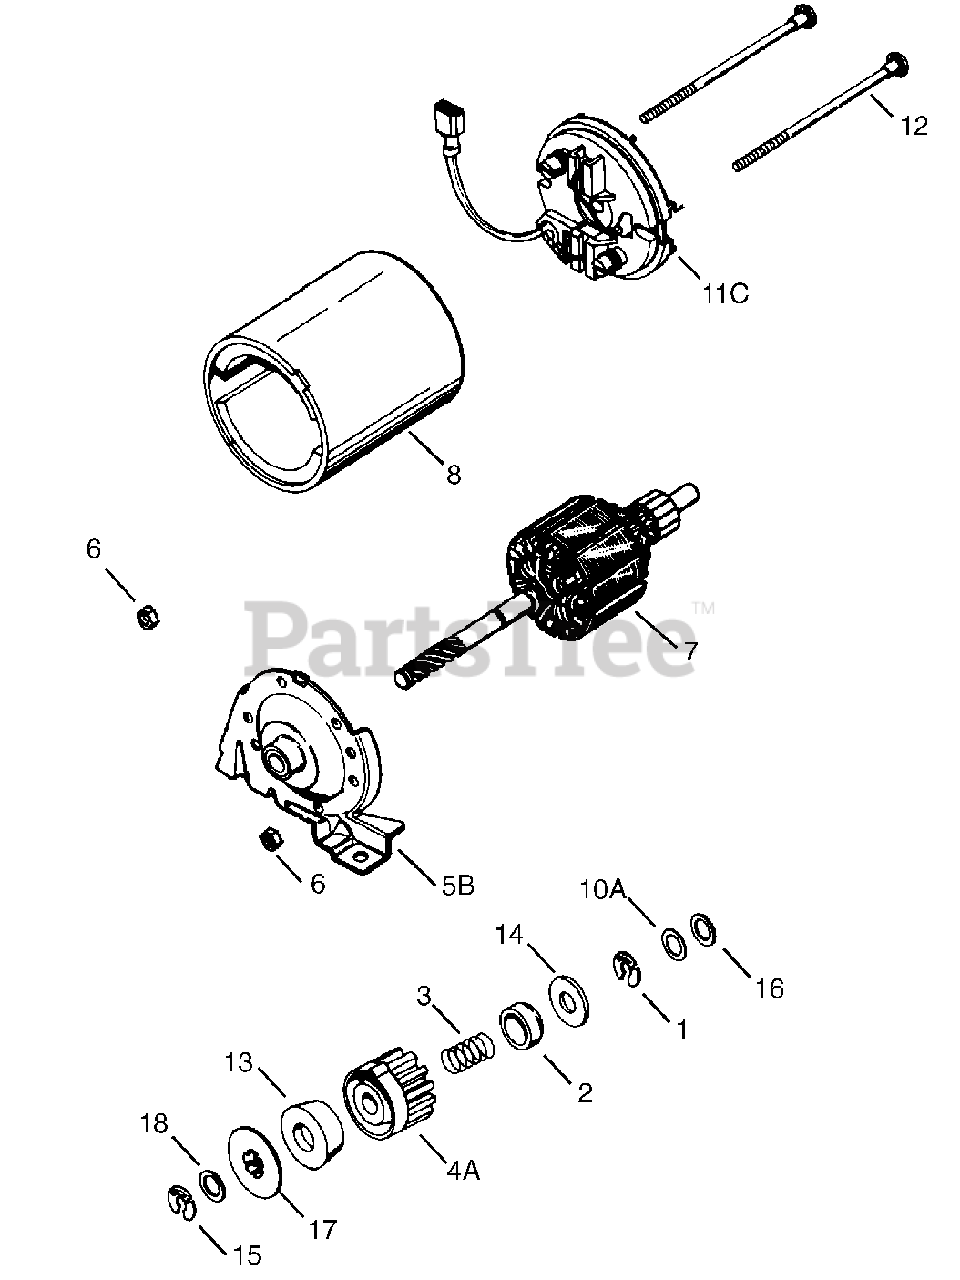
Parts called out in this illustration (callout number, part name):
1	Retainer Ring
2	Spring Retainer
3	Spring
4A	Gear
5B	Drive End Cap ASM
6	Lock Nut
7	Armature
8	Housing ASM
10A	Thrust Washer
11C	Commutator End Cap ASM (Incl. Brushes)
12	Bolt
13	Pinion Driver
14	Cup Washer
15	Retainer Ring
16	Washer
17	Drive Nut
18	Washer
